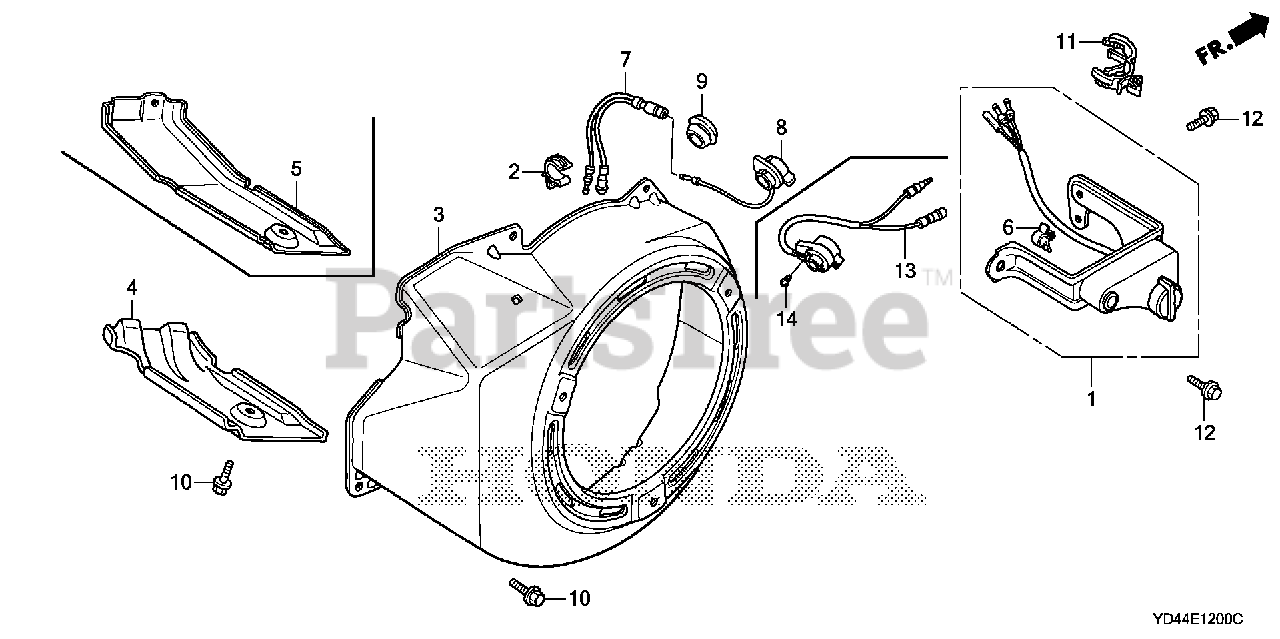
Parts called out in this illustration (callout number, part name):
2	CLIP, TUBE
3	COVER, FAN *R280* (POWER RED)
8	SWITCH ASSY., ENGINE STOP
10	BOLT, FLANGE (6X12) (CT200)
11	CLIP, WIRE HARNESS
